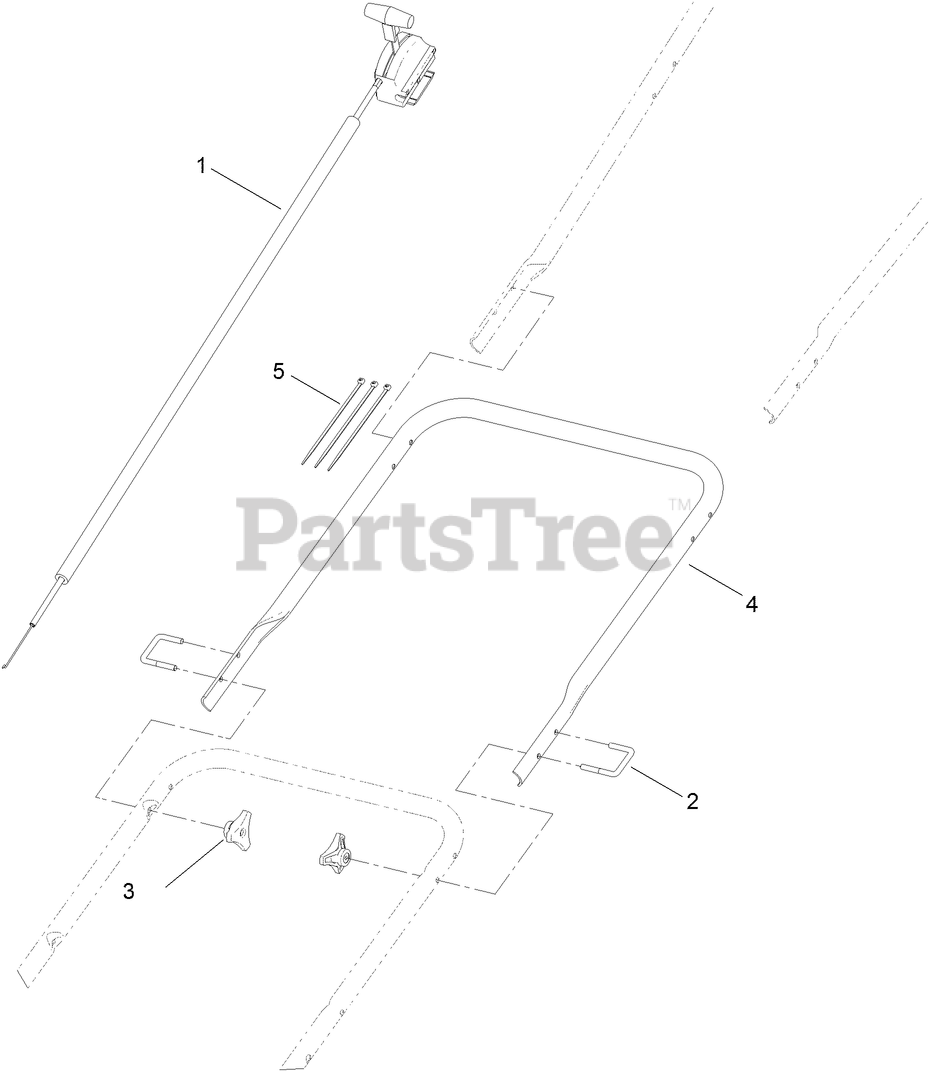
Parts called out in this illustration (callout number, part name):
1	THROTTLE CONTROL AND OPC ASM
2	BOLT-U
3	HANDWHEEL
4	EXTENSION-HANDLE
5	TIE-CABLE
